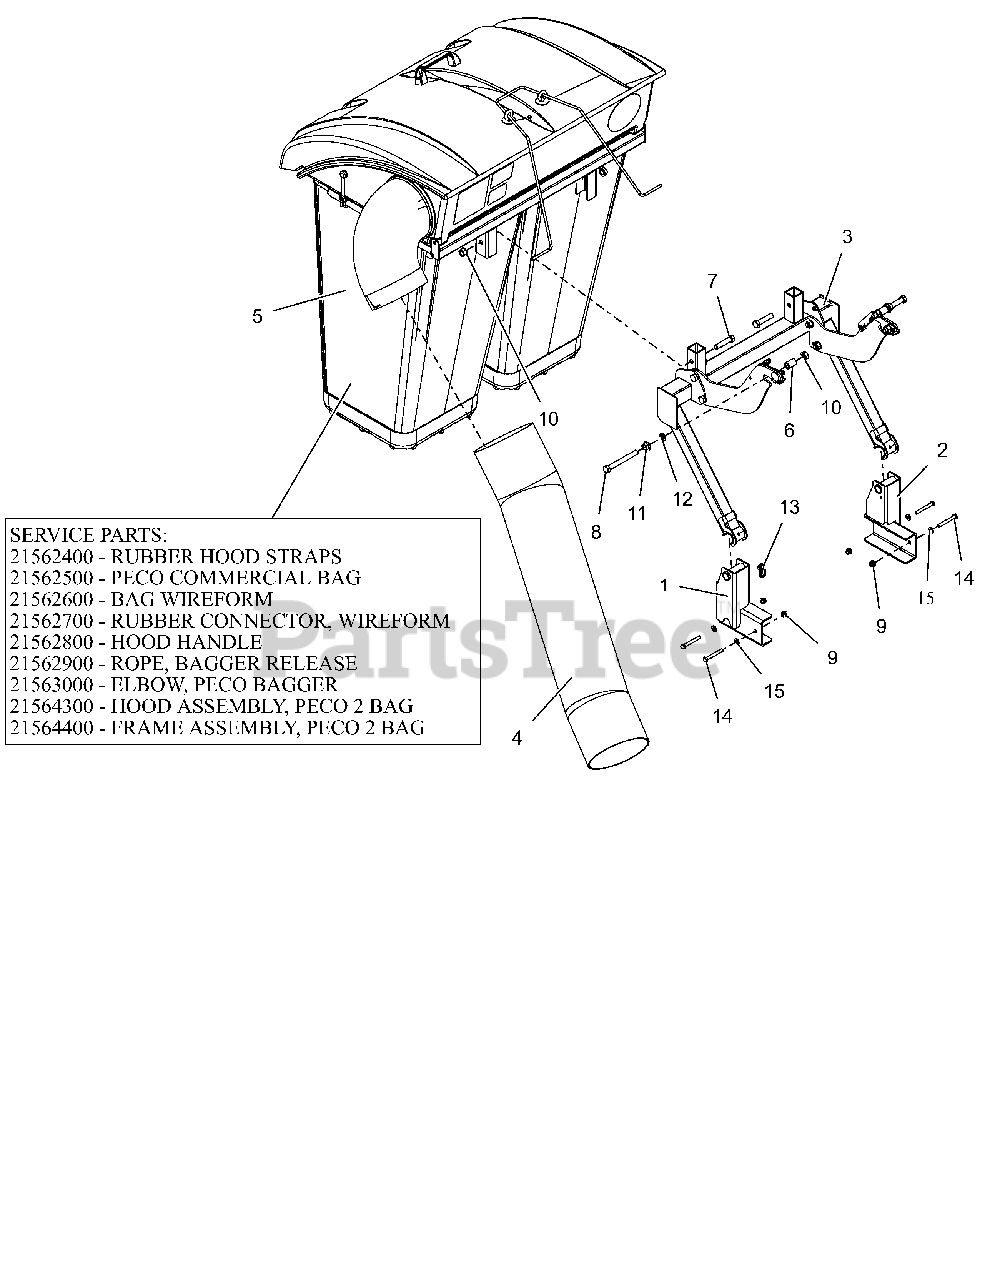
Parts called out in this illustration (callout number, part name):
1	WMT, BAGGER MNT RH PT/PT100
2	WMT, BAGGER MNT LH PT/PT100
3	WMT, BAGGER POST PT/PT100
4	HOSE BAGGER, 49"
5	BAGGER, PECO 2 BAG RECEPTACLE
5	RUBBER HOOD STRAP
5	BAG, MESH
5	BAG WIREFORM
5	RUBBER CONNECTOR - WIREFORM
5	HANDLE
5	ROPE, BAGGER RELEASE
5	ELBOW, PECO BAGGER
5	HOOD ASM PECO 2 BAG
5	FRAME ASM PECO 2 BAG
6	SPACER .510 X .75 X 1.1485
7	@BLT-HEX .50-13X2.25 GR5 YWZC
8	@BLT-HEX .5-13-4.5GR8 FULL THD
9	@NUT-LK-NYL-FLG .31-18 YWZC
10	@NUT-LK-TOP-FLG .50-13 YWZC
11	NUT-SPNLK-FLG .50-13 YWZC
12	WSHR-FL-STL .505X.880X.072 YWZ
13	CABLE TIE W/ TREE (.25 HOLE)
14	@BLT-HEX .31-18X2.50 GR5 YWZC
15	@WSHR-FL-STL.344X.688X.065YWZC
